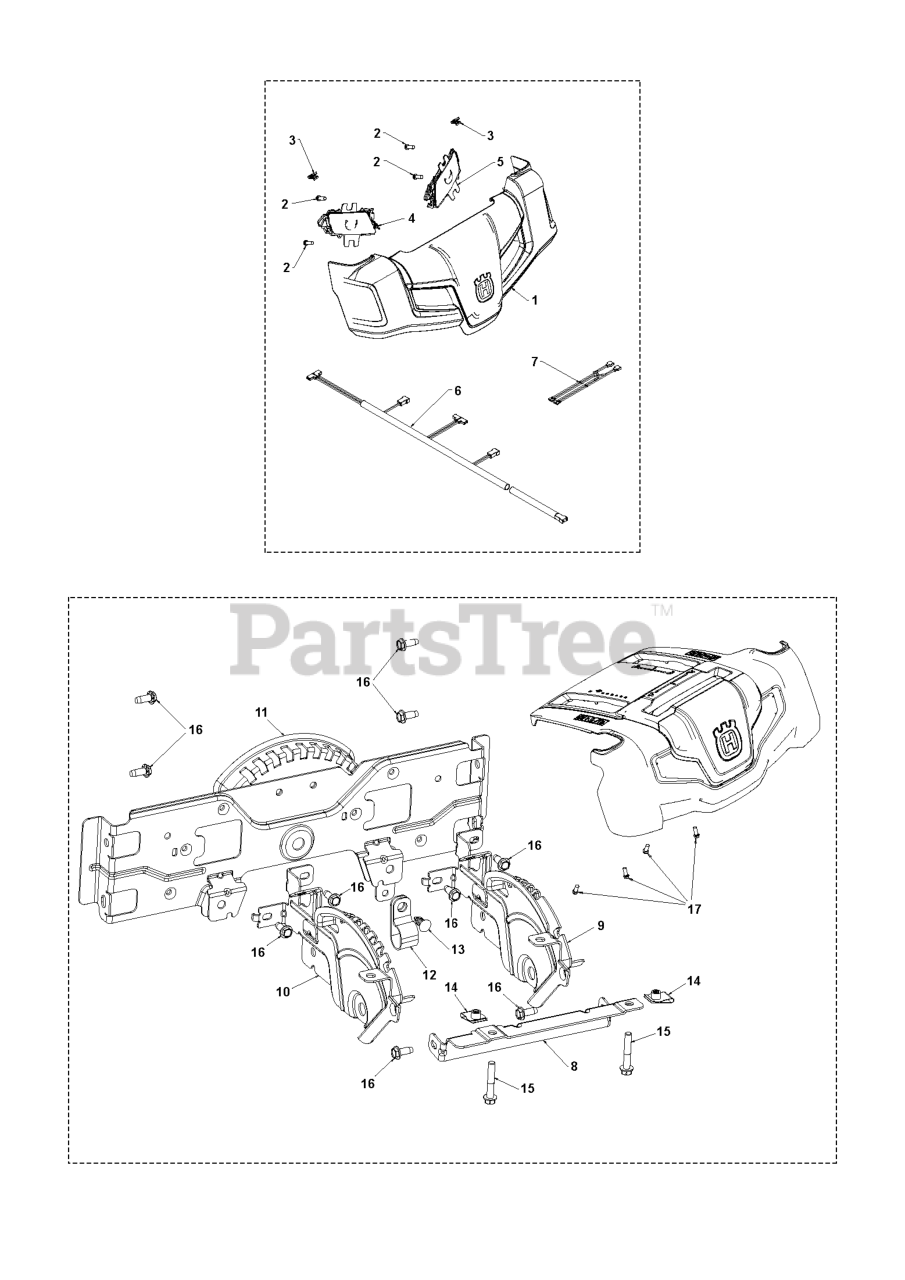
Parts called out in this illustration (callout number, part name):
1	COVER CONSOLE_ASM_HUSQVARNA
2	SCREW.HWH.13-16-5.8.BZP
3	CLIP PANEL ERGO 30603
4	LIGHT ASM.HUSQVARNA.RH
5	LIGHT ASM.HUSQVARNA.LH
6	RP HARNESS.WIRE.LIGHT & GRIP
7	HARNESS.WIRE.LIGHT.JUMPER
8	Brackets
9	Brackets
10	Brackets
11	Brackets
12	CLIP.CABLE.BLK
13	FASTENER.PUSH.O.250X0.783
14	NUT.U-CHNL.1/4-20.550DP.350PNL
15	SCREW.HEXCAP.1/4X-20X1.500
16	HEX.WASHER.HEAD 1/4-20 X .65
17	SCREW.HWH.13-16-5.8.BZP
